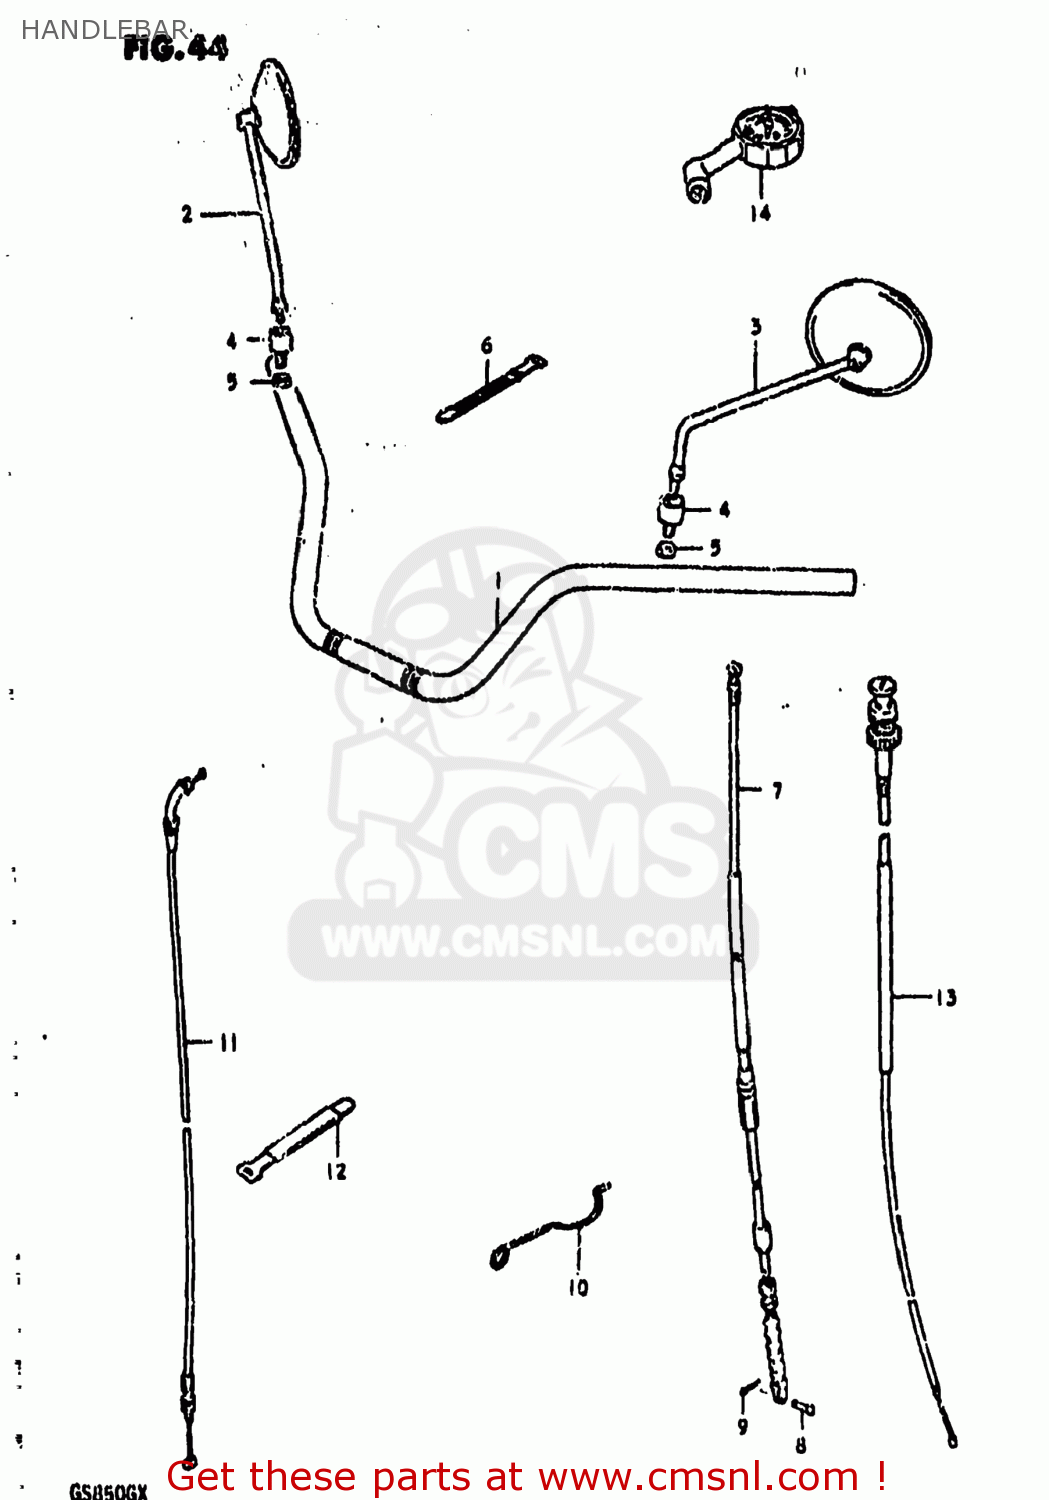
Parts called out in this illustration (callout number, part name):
1	HANDLEBAR
2	MIRROR ASSEMBLY,RIGHT
3	MIRROR ASSEMBLY,LEFT
4	CUSHION,REAR VIEW MIRROR
5	NUT
6	CLAMP(L:120)
7	CABLE ASSY,CLUTCH
8	PIN(L:15)
9	PIN
10	GUIDE,CABLE
11	CABLE ASSEMBLY,THROTTLE
12	CLAMP
13	CABLE ASSEMBLY,STARTER
14	GAUGE ASSY,AIR PRESSURE
